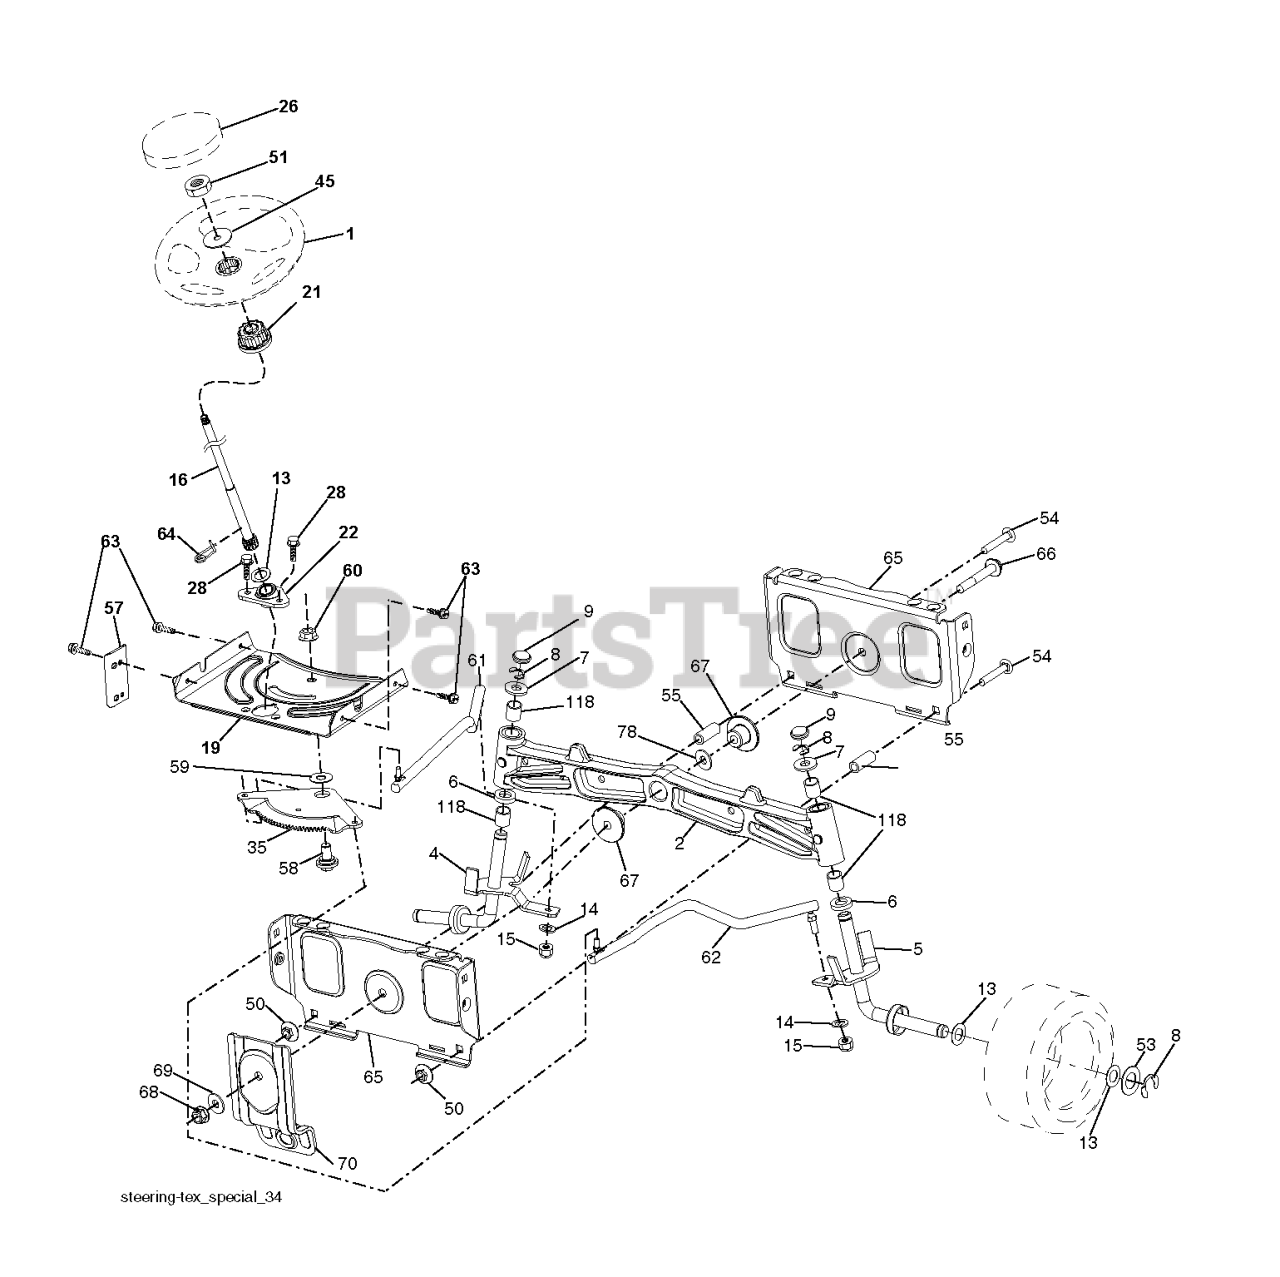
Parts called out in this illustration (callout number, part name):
1	RP WHEEL.STEER.HUSQ.PREM.OVMLD
2	AXLE.SVC.ASM CAST IRON.TEX
4	SPINDLE.WELDED.LH.16"TEX
5	SPINDLE.WELDED.RH.16"TEX
6	THRUST WASHER
9	CAP.SPINDLE.BLACK
14	WASHER, LOCK 3/8
15	NUT CROWNLOCK 3/8-24
16	SHAFT.STEER.STEALTH.DD
19	PLATE.STEER.DDL.NLT/NG
21	ADAPTER, WHEEL STNG..
22	STEERING.SUPT.LOWER.
26	RP INSERT.CAP.WHL.STRG.HUSQ.
28	SCREW, 3/8-16X3/4
35	GEAR.SECTOR.PLATE.DDL.
45	WASHER 9/16"ID, 2 3/8"OD
50	NUT LOCK FLG 3/8-16 UNC
51	NUT.HEX.1/2-20
53	WASHER.HARDENED
55	SPACER.BRACE.AXLE
58	BOLT.SHOULDER.SECTOR.P
59	WASHER.THURST.SECTOR.S
60	NUT FLANGE LOCK 5/8-11
61	DRAGLINK.LH.BALLSTUD.D
62	DRAGLINK.RH.BALLSTUD.D
63	SCREW
64	RETAINER.CLIP.SPRING.S
65	BRACE.AXLE.FRONT.NLT/N
66	BOLT HEX FGHD 7/16-14 X 3 SERR
67	BUSHING.PM.FRONT AXLE
68	NUT.LOCK.FLANGE.7/16
69	WASHER.1.5X.505X.118
70	BRKT.DECK.SUSPENSION.F
78	THRUST WASHER
118	BUSHING, AXLE CAST
